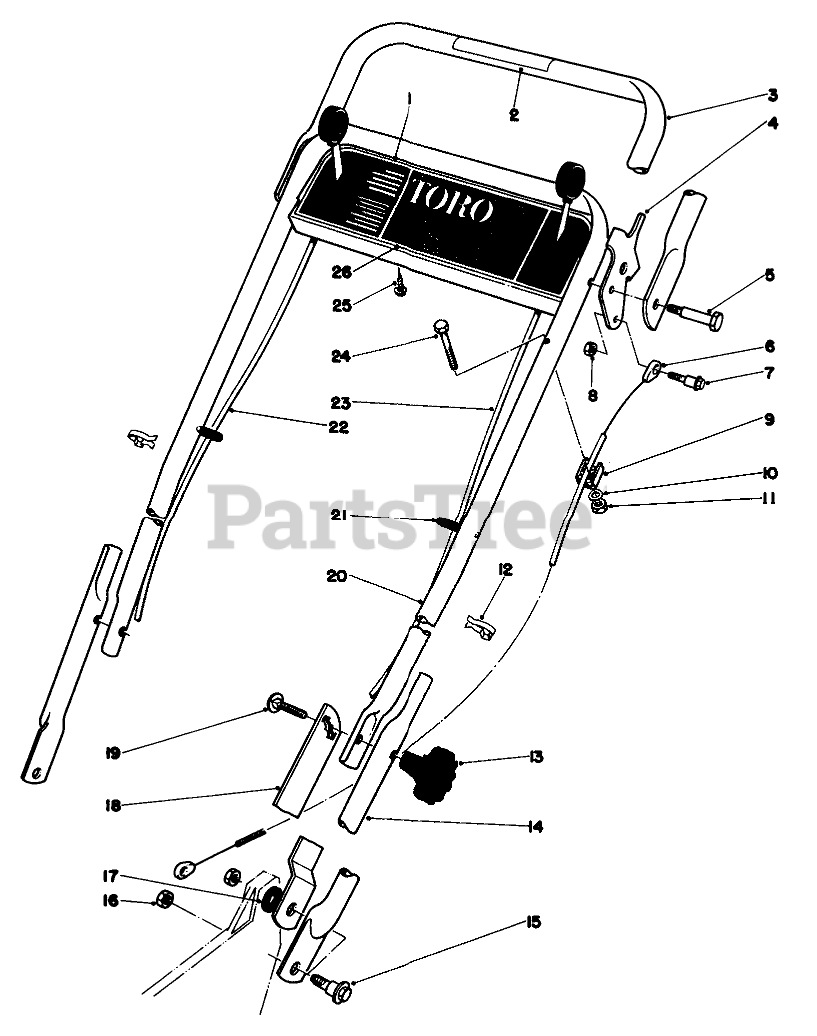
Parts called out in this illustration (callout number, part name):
1	Control Panel
2	Decal-Traction Control
3	Demand Handle
4	Demand Handle Stop
5	BOLT-SHOULDER
6	DEMAND HANDLE CABLE
7	Shoulder Bolt
8	NUT-HEX, SIDE DEFORM
9	CLAMP-CABLE
10	WASHER-FLAT
11	NUT-LOCK, NI
12	BOWDEN CLIP
14	LOWER HANDLE
15	Screw
16	Nut
17	SPACER
18	Handle Latch L.H.
19	SCREW-CARR
20	Upper Handle
21	CAP-VINYL
22	GROUND SPEED CONTROL
23	Throttle Control
24	SCREW-HH
25	SCREW-HWHTF
26	Decal Control Panel
